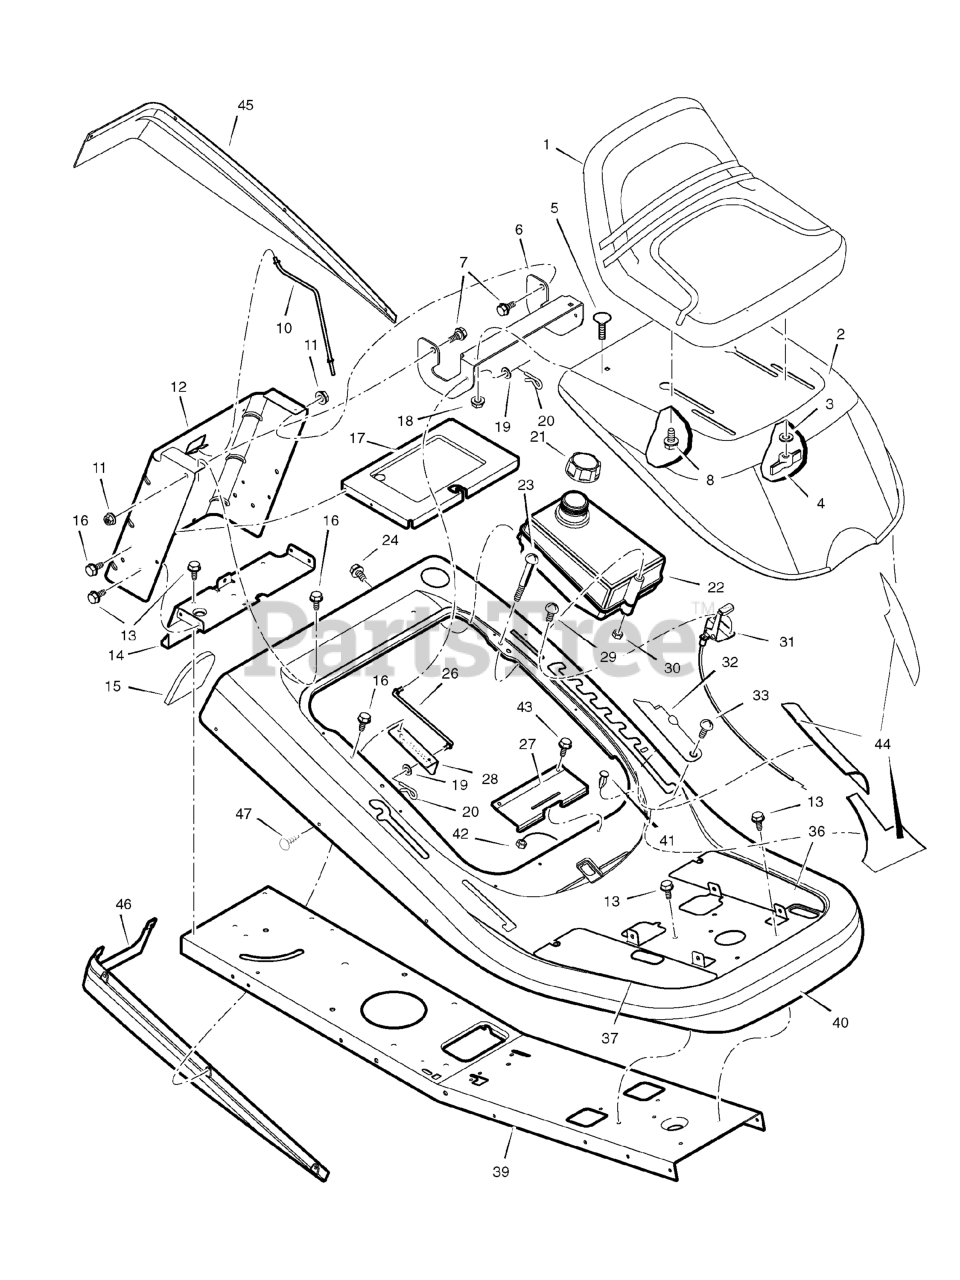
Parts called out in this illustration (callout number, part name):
1	Seat
3	Washer
4	Bolt, Wing
5	Bolt, Carriage
6	Bracket, Hinge
7	Bolt, Shoulder
8	Bolt, Shoulder
10	Rod, Battery
11	Nut, Flange
12	Plate, Rear
14	Plate, Hitch
17	TRAY, Battery
18	Nut, Flange
19	Washer
20	Pin, Cotter
21	Cap, Fuel Tank
22	Tank, Fuel
23	Screw
26	Rod, Hood Prop
27	Spring, Seat Deck
28	Bracket, Prop Rod
30	Nut, NY Lock
31	Control, Throttle
32	Cover, Detent (Gray)
33	Bolt, Shoulder
36	Footmat, Left
37	Footmat, Right
42	Nut
43	Screw
44	Kit, Foil Heat Shield
45	Trim, Left (Gray)
46	Trim, Right (Gray)
47	Fuel Tank Assembly
